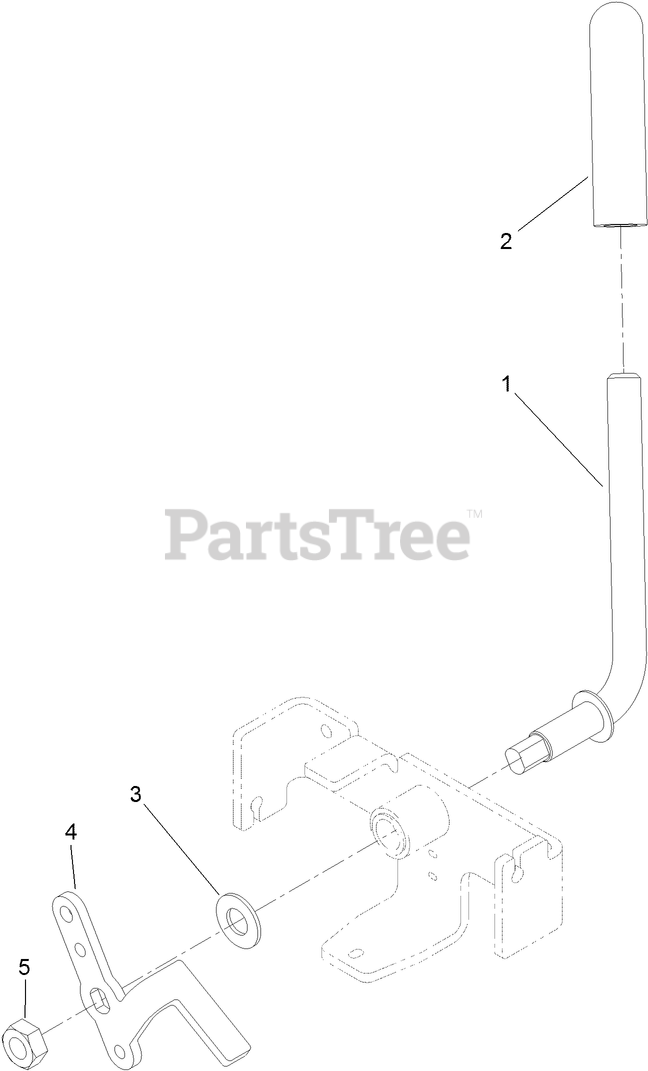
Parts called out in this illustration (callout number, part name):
1	LEVER-BRAKE
2	GRIP-HANDLE
3	WASHER-FLAT
4	SEE BULLETIN SWS #110
5	NUT-LOCK, NI
